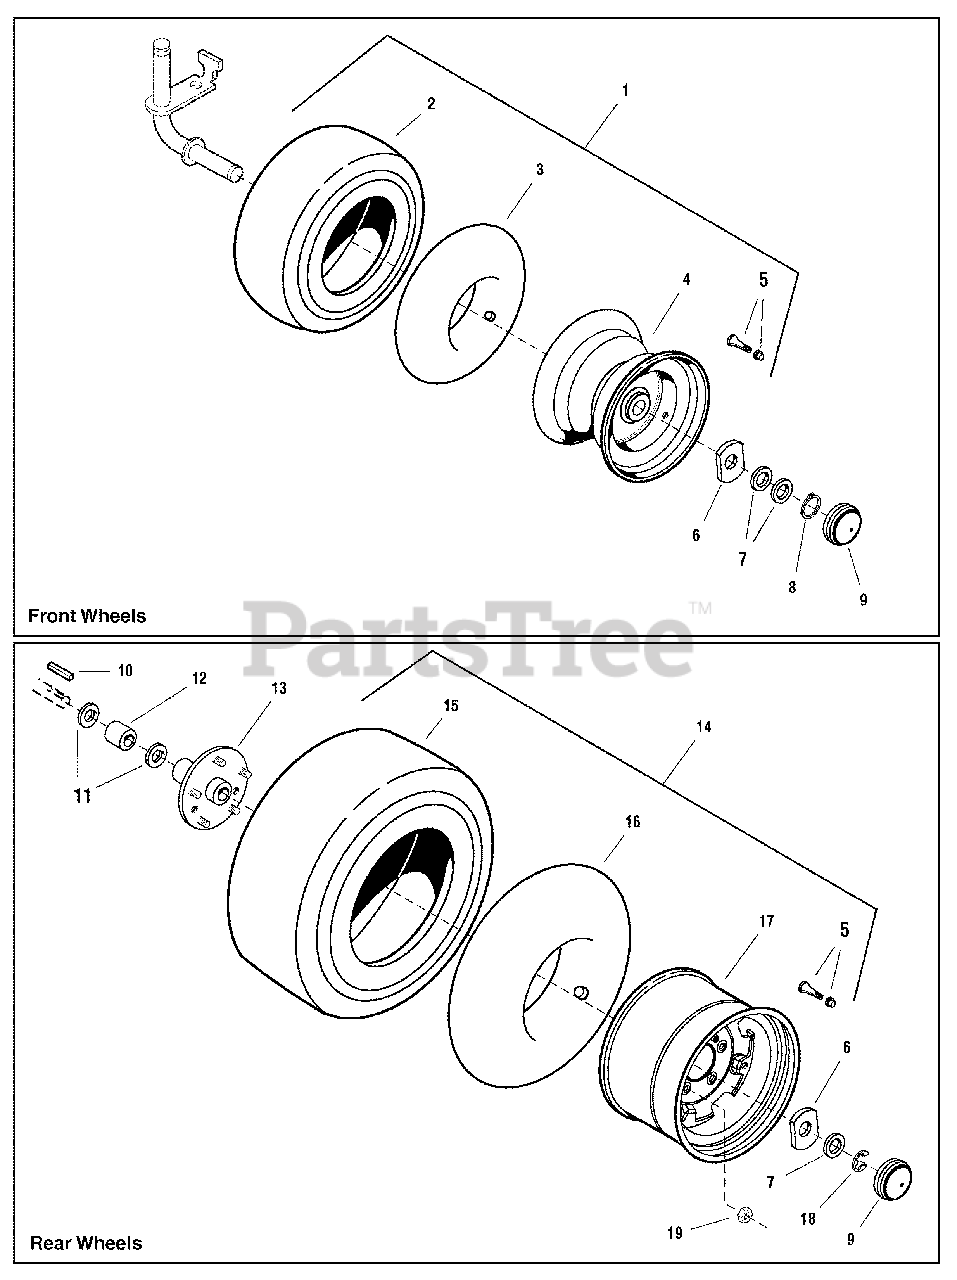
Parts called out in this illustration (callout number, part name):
1	WHEEL & TIRE ASSEMBLY, Front
2	TIRE, 16 x 6-1/2 - 8 Super Turf, Front
3	TUBE, Tire 16 x 6-1/2 - 8, Front
4	WHEEL, 5 3/8 x 7-15/16, Front
5	VALVE STEM & CAP ASSEMBLY
6	WASHER, Special, 1 x 2-1/2
7	WASHER
8	RING, Shaft
9	CAP, Hub Grey, 2-23/64
10	KEY, HI PRO, 1/4 x 2
11	WASHER
12	SPACER, 1-1/16 x 1-1/2 x 1-23/32, Black
13	PLATE & HUB ASSEMBLY, Rear Wheel w/Studs
14	WHEEL & TIRE ASSEMBLY, Rear 23"
15	TIRE, 23 x 10-1/2 - 12 Super Turf, Rear
16	TUBE, Tire 23 x 10-1/2 - 12, Rear
17	WHEEL, 7 x 12, Rear
18	RING, Shaft
19	NUT, Hex 7/16-20, For Wheel Bolt
